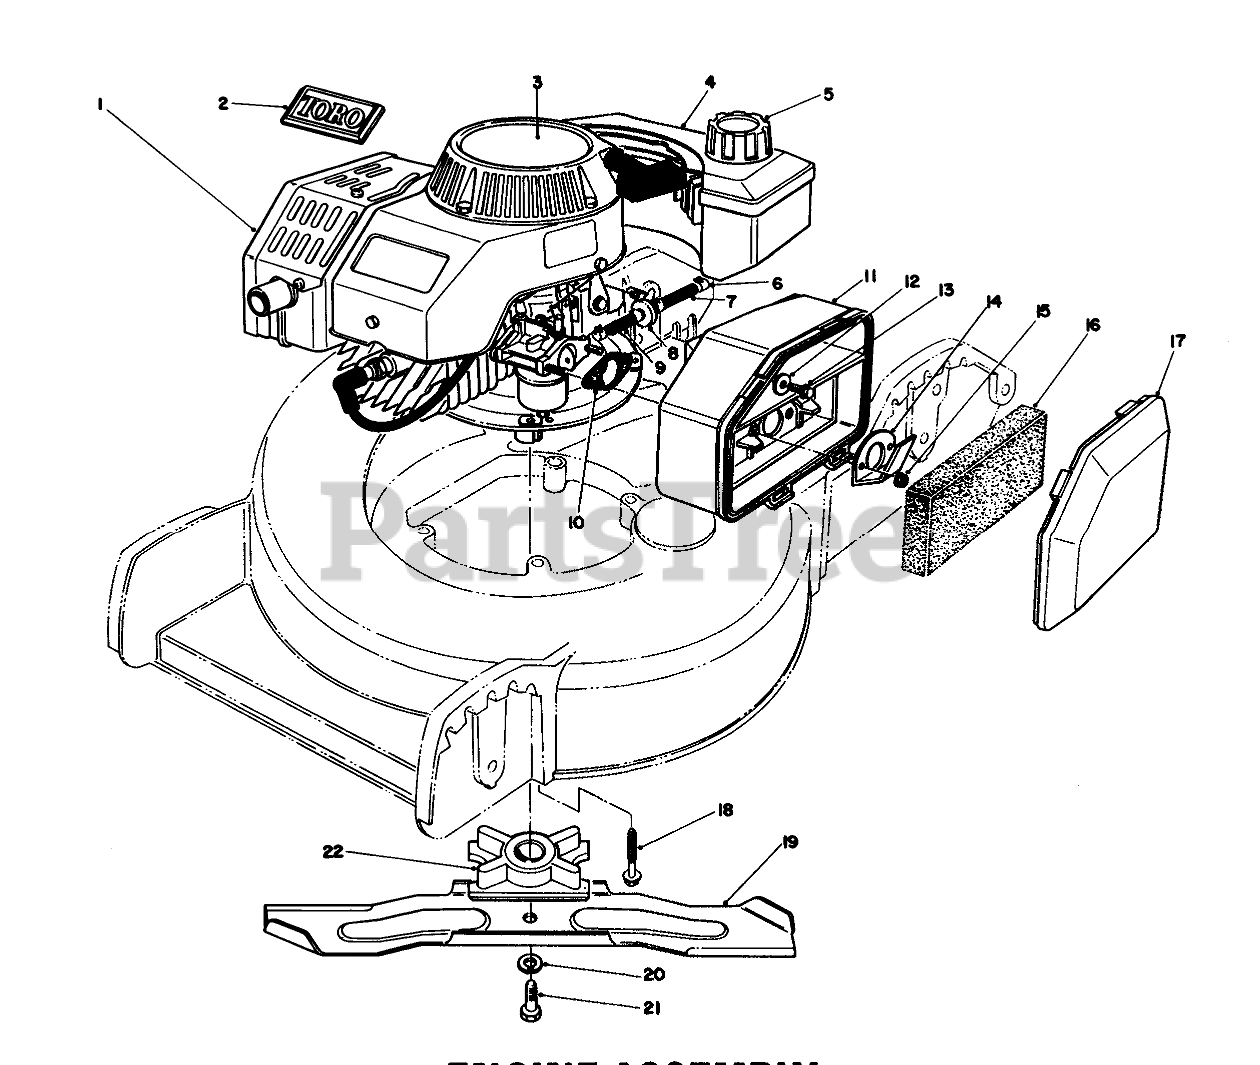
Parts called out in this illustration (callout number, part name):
1	Engine
2	TORO LOGO PLT
3	DECAL- 2 CYC RECOIL
4	Gas Tank Assembly
5	GAS CAP ASM
6	CLAMP-FUEL LINE
7	HOSE-FUEL
8	FILTER-FUEL
9	HOSE-FUEL
10	GASKET-AIR CLEANER
11	AIR CLEANER
12	WASHER-FLAT
13	SCREW-HH
14	SPIT BACK DEFLECTOR
15	NUT-LOCK
16	FILTER
17	AIR CLEANER COVER
18	SCREW-HHF
19	Blade
20	WASHER-LOCK
21	SCREW-HH
22	BLADE RETAINER
